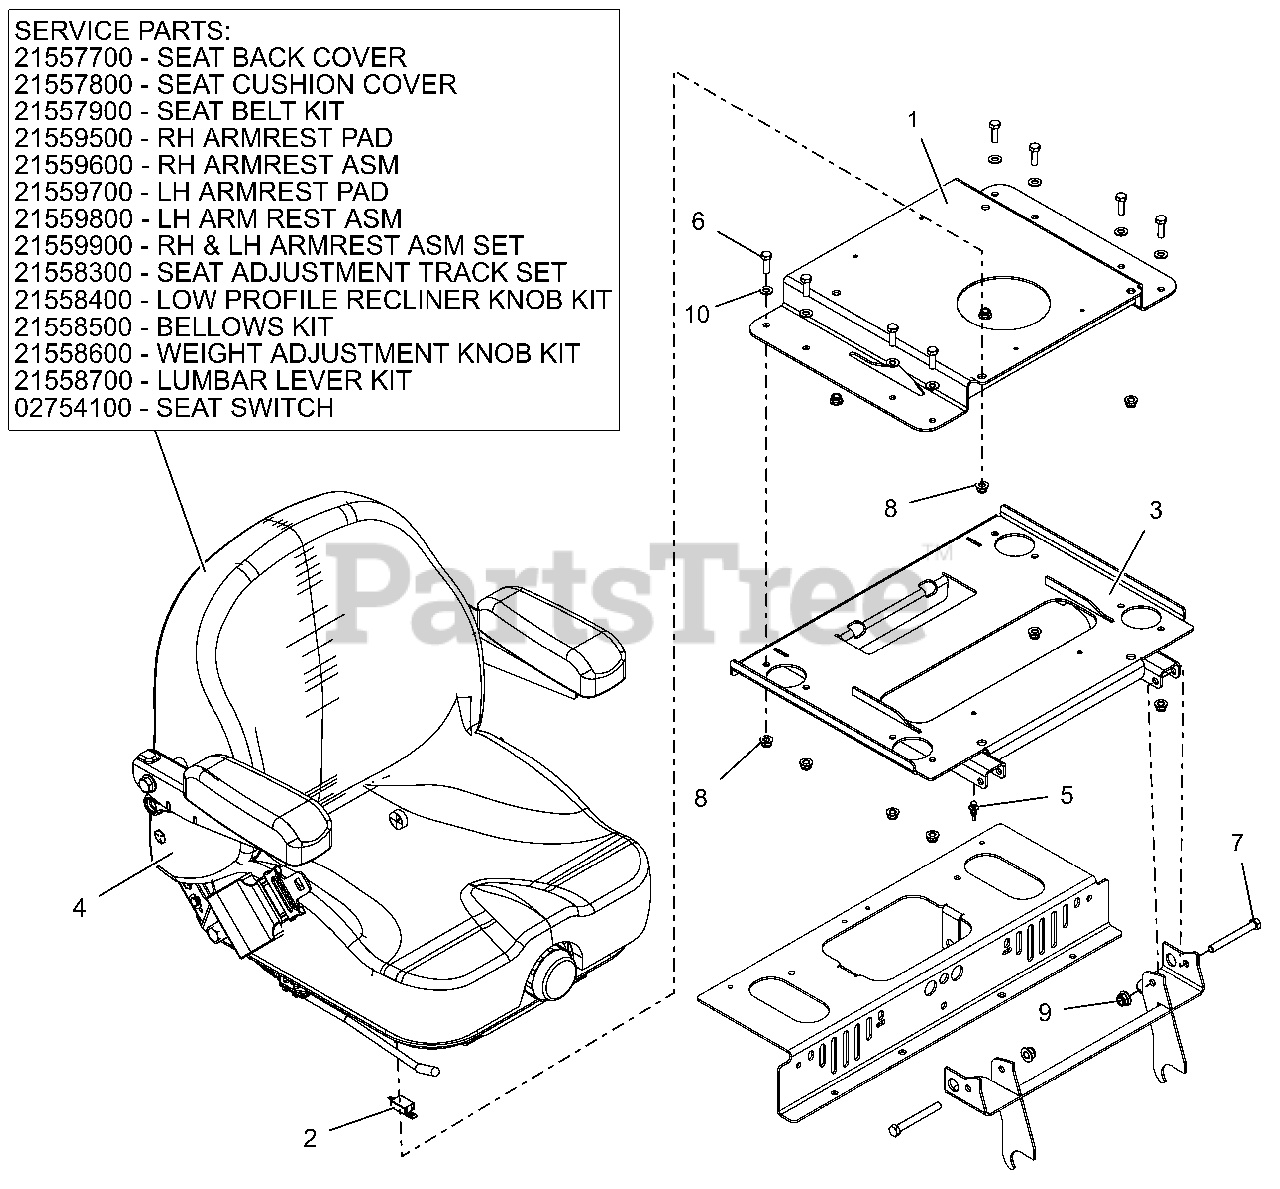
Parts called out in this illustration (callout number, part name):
1	SEAT BASE MOUNTING WLDM - RED
2	HARNESS, PT200 SEAT ADAPTER
3	SEAT ISO MOUNTING WLDMT - RED
4	SEAT, FULL SUSPENSION
5	CABLE TIE W/ TREE (.25 HOLE)
6	@BLT-HEX .31-18X1.00 GR5 YWZC
7	@BLT-HEX .38-16X3.25 GR5 YWZC
8	@NUT-LK-NYL-FLG .31-18 YWZC
9	@NUT-LK-NYL-FLG .38-16 YWZC
10	@WSHR-FL-STL.344X.688X.065YWZC
